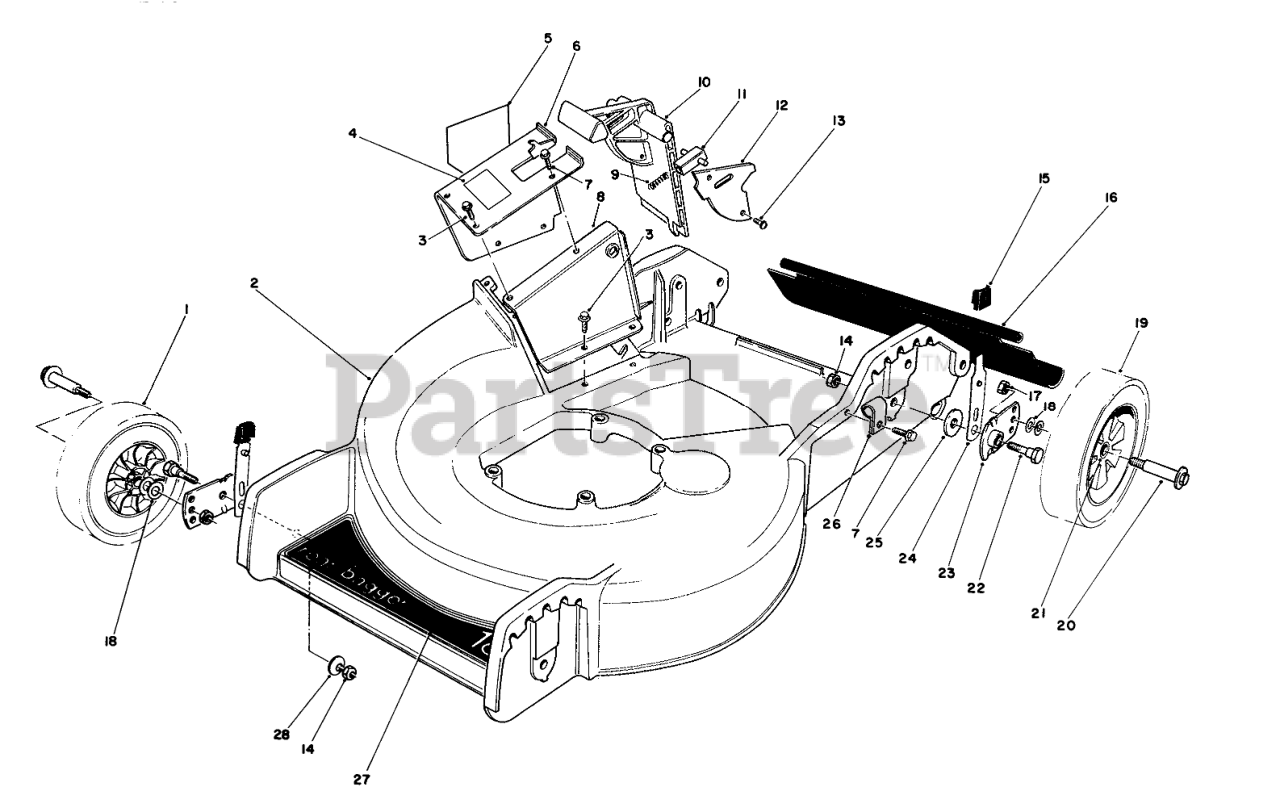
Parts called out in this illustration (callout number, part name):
1	Wheel & Tire Assembly (Incl. Ref. #21)
2	HSG & CARTON
3	SCREW
4	Decal-Door
5	DECAL-DANGER
6	Tunnel-Outer (Incl. Ref. #4 & 5)
7	SCREW
8	Tunnel-Inner
9	SPRING-COMPRESSION, LATCH
10	Door Mulching
11	Door Latch
12	Cover Door
14	NUT-LOCK, NI
15	KNOB-ARM
16	SHIELD - TRAILING
17	Nut
18	WASHER
19	Wheel & Tire Assembly (Incl. Ref. #21)
20	BOLT-WHEEL
21	BUSHING
22	5/16-18 PIVOT SCREW
23	PIVOT ARM ASSY
24	SPRING ARM ASM
25	PIVOT WASHER
26	CLAMP-NYLON
27	DECAL-DECK
28	WASHER-BELLEVILLE
